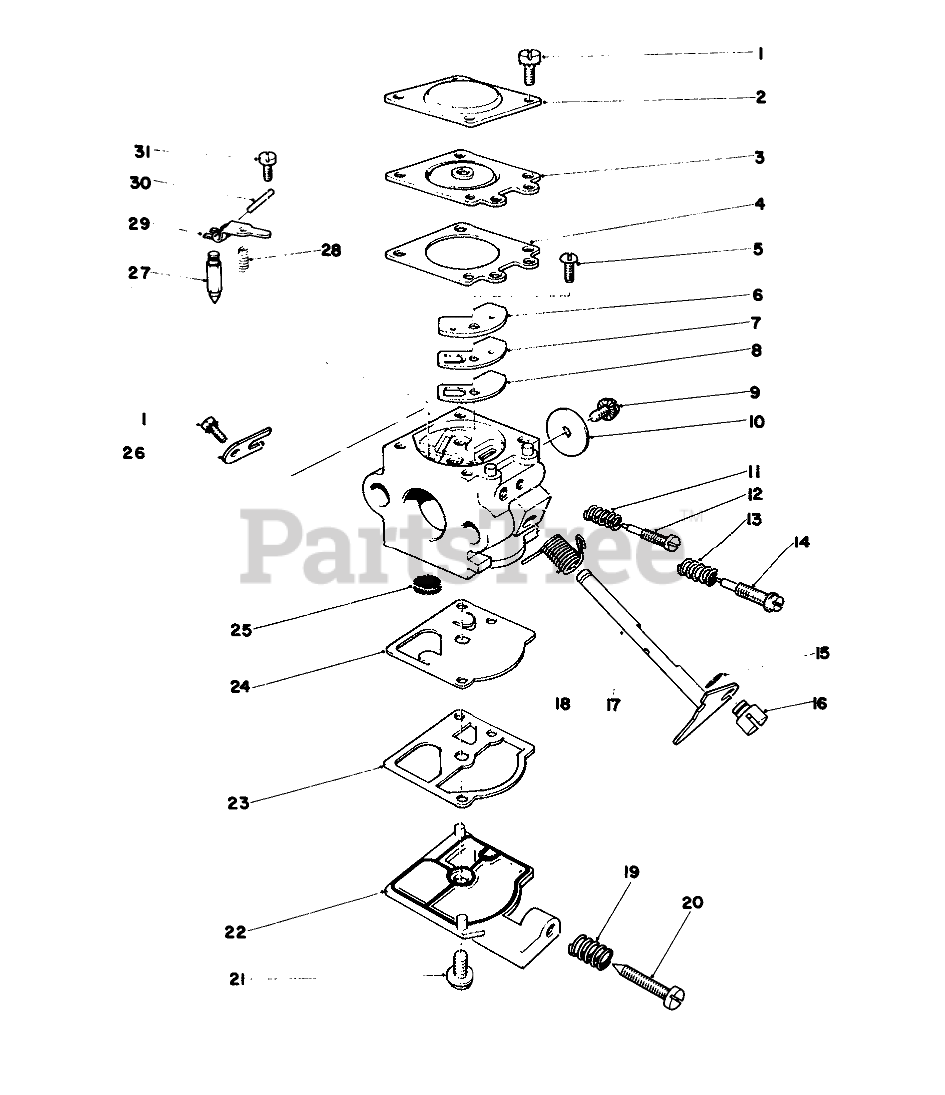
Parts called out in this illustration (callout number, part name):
1	Screw
2	Cover, Diaphragm
3	METERING DIAPHRAGM
4	Gasket, Diaphragm
5	Screw-Circuit Plate
6	Plate, Circuit
7	Diaphragm Circuit Plate
8	Gasket-Circuit Plate
9	Screw
10	Valve, Throttle
11	Spring, Needle
12	Idle Needle
13	Spring, HS Needle
14	Needle, HS
16	Swivel
17	Decal-Choke
18	Spring-Throttle Lever
20	Screw, Idle Adjust
21	Decal Fuel Mix
22	Cover, Fuel Pump
23	PUMP GASKET
24	Diaphragm Fuel Pump
25	Screen Inlet
26	Clip Throttle Shaft
27	INLET NEEDLE VALVE
28	Spring, Lever
29	Lever Metering
30	Metering Lever Pin
31	Screw-Metering Pin
